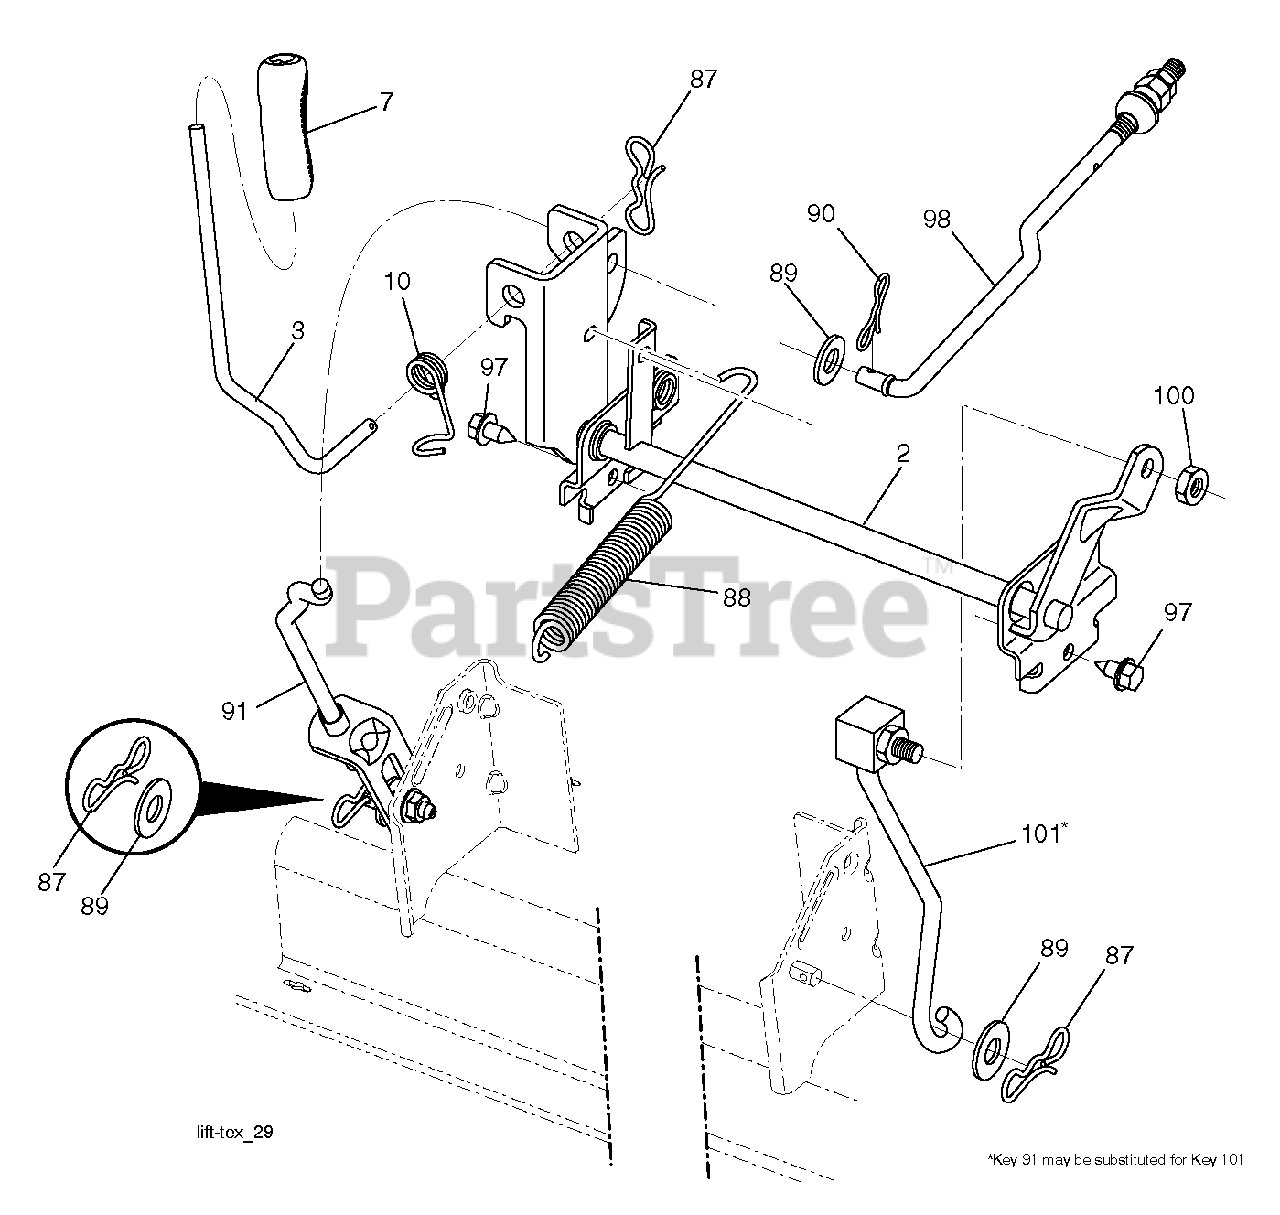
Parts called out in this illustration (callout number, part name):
2	SHAFT.ASM.CROSS.LIFT
3	LEVER.LIFT.HANDLE.LT
7	GRIP.HANDLE.LIFT.PVC.BLACK
10	SPRING.TORSION.LIFT.HANDLE
87	PIN.COTTER.7/16.BOW TI.
88	SPRING.LIFT.ASSIST
89	WASHER.CLEAR.ZINC
90	PIN.COTTER.5/16.BOW TI
91	LINK.ASM.LIFT.REAR
97	SCREW, 3/8-16X3/4
98	LINK.ASM.SUSP.FRONT.MW
100	LOCKNUT
101	LINK.ASM.LIFT.FIXE.38/42/46"
